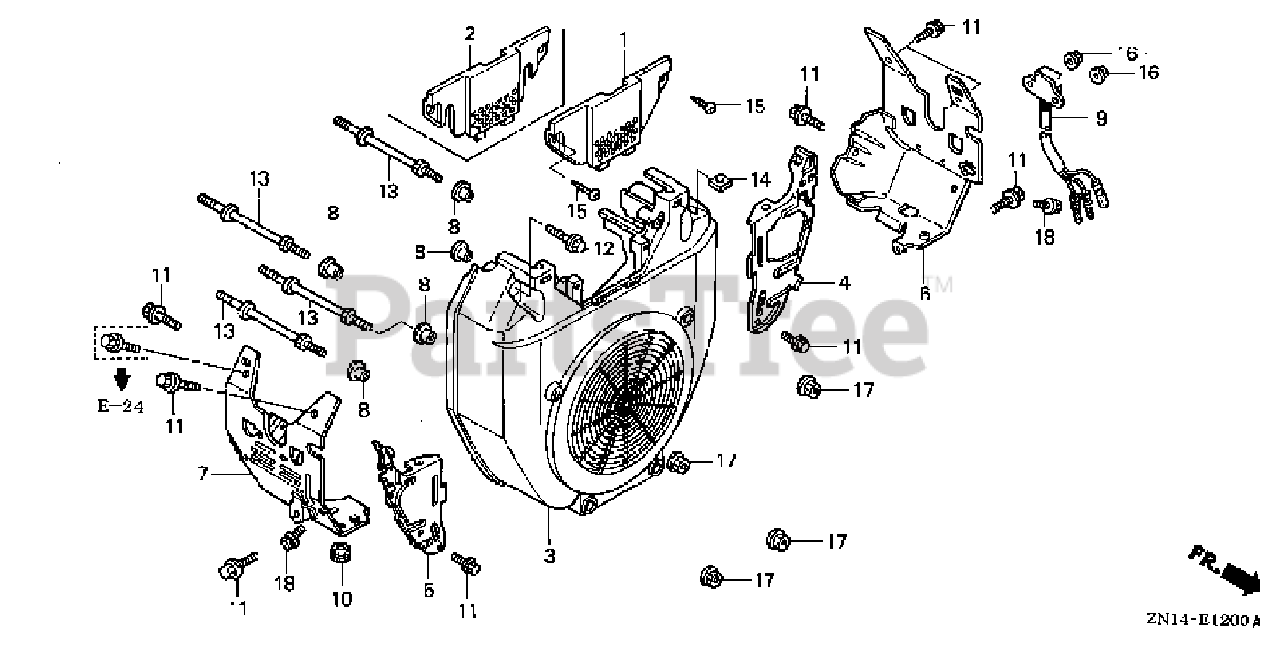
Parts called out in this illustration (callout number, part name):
2	COVER, FUEL PUMP (MANUAL CONTROL)
3	COVER, FAN *NH1* (BLACK)
3	COVER, FAN *R8* (BRIGHT RED)
4	PLATE, R. SIDE
5	PLATE, L. SIDE
6	SHROUD, R. (OIL ALERT)
7	SHROUD, L.
8	COLLAR B, TAILLIGHT
9	ALERT UNIT ASSY., OIL
10	RUBBER, RR. FENDER CUSHION
11	BOLT, FLANGE (6X12) (CT200)
12	BOLT, FLANGE (6X23)
13	BOLT, STUD (6X71)
14	NUT, SQUARE (5MM)
15	SCREW, TAPPING (5X20)
16	NUT, FLANGE (5MM)
17	NUT, FLANGE (6MM)
18	BOLT, FLANGE (6X8)
